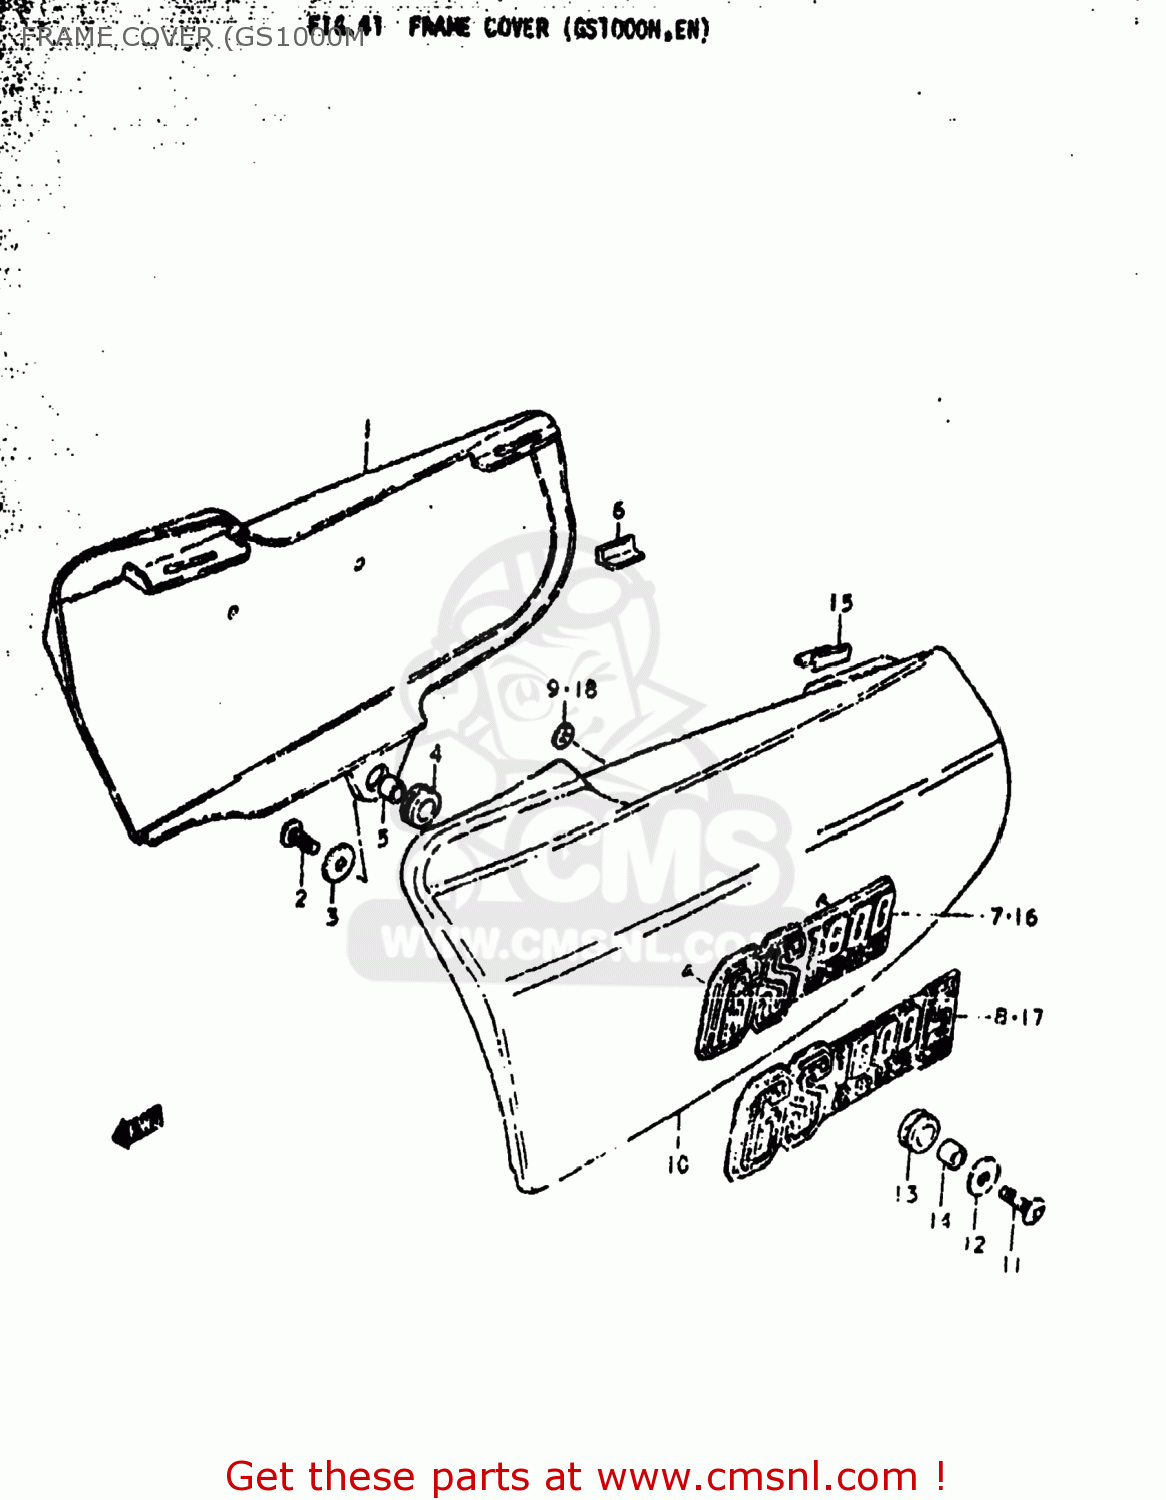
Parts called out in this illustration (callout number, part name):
1	COVER,FRAME,RIGHT
2	SCREW (6X20)
3	WASHER (6.5X18X1.6)
4	CUSHION
5	SPACER (6.8X10X10)
6	CUSHION,FRAME COVER
7	EMBLEM,FRAME COVER
8	EMBLEM,FRAME COVER
9	NUT
10	COVER,FRAME,LEFT
11	SCREW (6X20)
12	WASHER (6.5X18X1.6)
13	CUSHION
14	SPACER (6.8X10X10)
15	CUSHION,FRAME COVER
16	EMBLEM,FRAME COVER
17	EMBLEM,FRAME COVER
18	NUT
